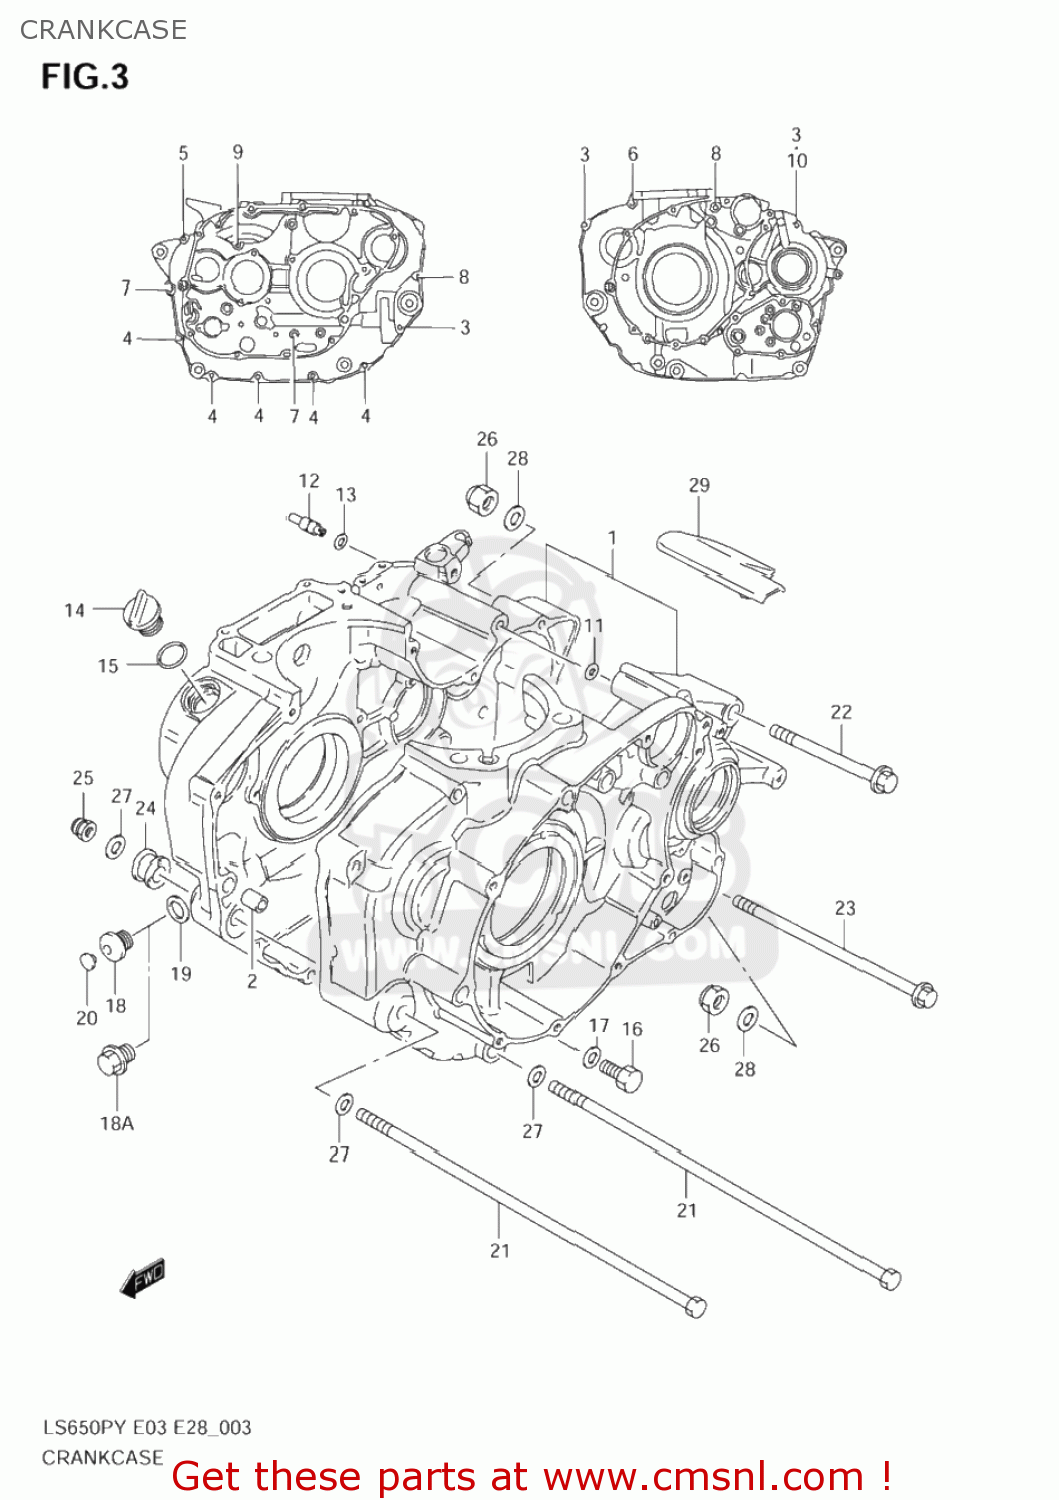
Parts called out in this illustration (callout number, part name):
1	CRANKCASE SET
2	PIN(8.4X11X20)
3	BOLT
4	BOLT
5	BOLT
6	BOLT
7	BOLT
8	BOLT
9	BOLT
10	GASKET(5.8X11X1.2) (NAS)
11	O RING(D:2.4,ID:9.6)
12	JET,OIL GALLERY(18)
13	O RING(D:1.2,ID:4)
14	PLUG(20X10)
15	O RING(D:3.1,ID:16.8)
16	BOLT
17	GASKET(12.1X16.2X3.7) (NAS)
18	PLUG,14X12
18A	PLUG (14X12)
19	GASKET(13.8X18.8X4.8) (NAS)
20	CAP(OD:12)
21	BOLT(10X323)
22	BOLT(10X105)
23	BOLT(10X180)
24	SPACER,ENGINE MOUNT(L20)
25	NUT
26	NUT
27	WASHER
28	WASHER
29	COVER,CRANKCASE START MOT
